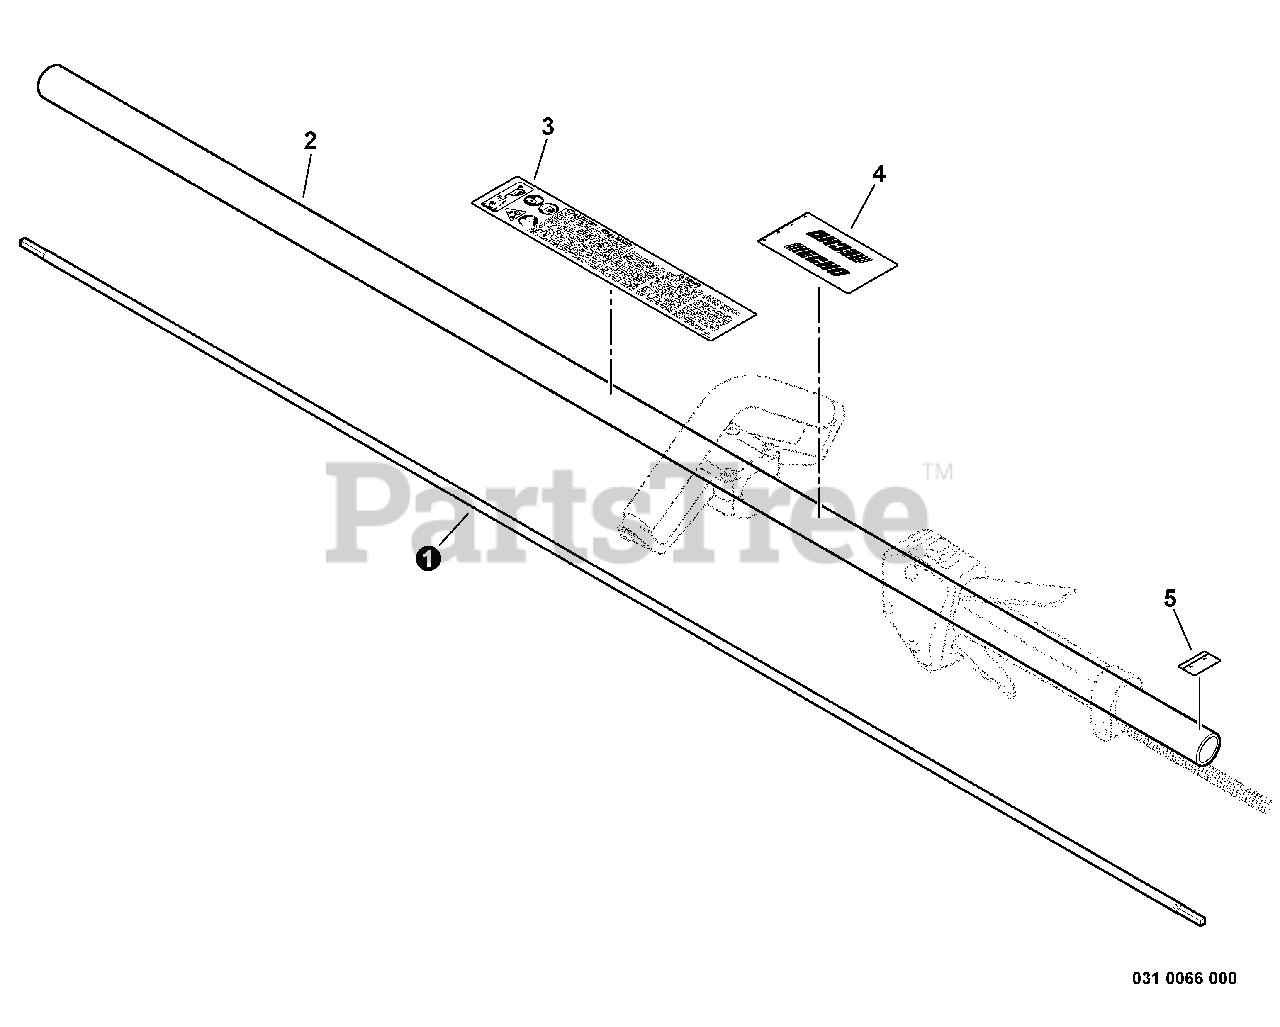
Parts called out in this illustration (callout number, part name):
1	DRIVESHAFT
2	PIPE, MAIN
3	LABEL, CAUTION
4	LABEL, HANDLE LOCATION
5	LABEL - ALIGNMENT
